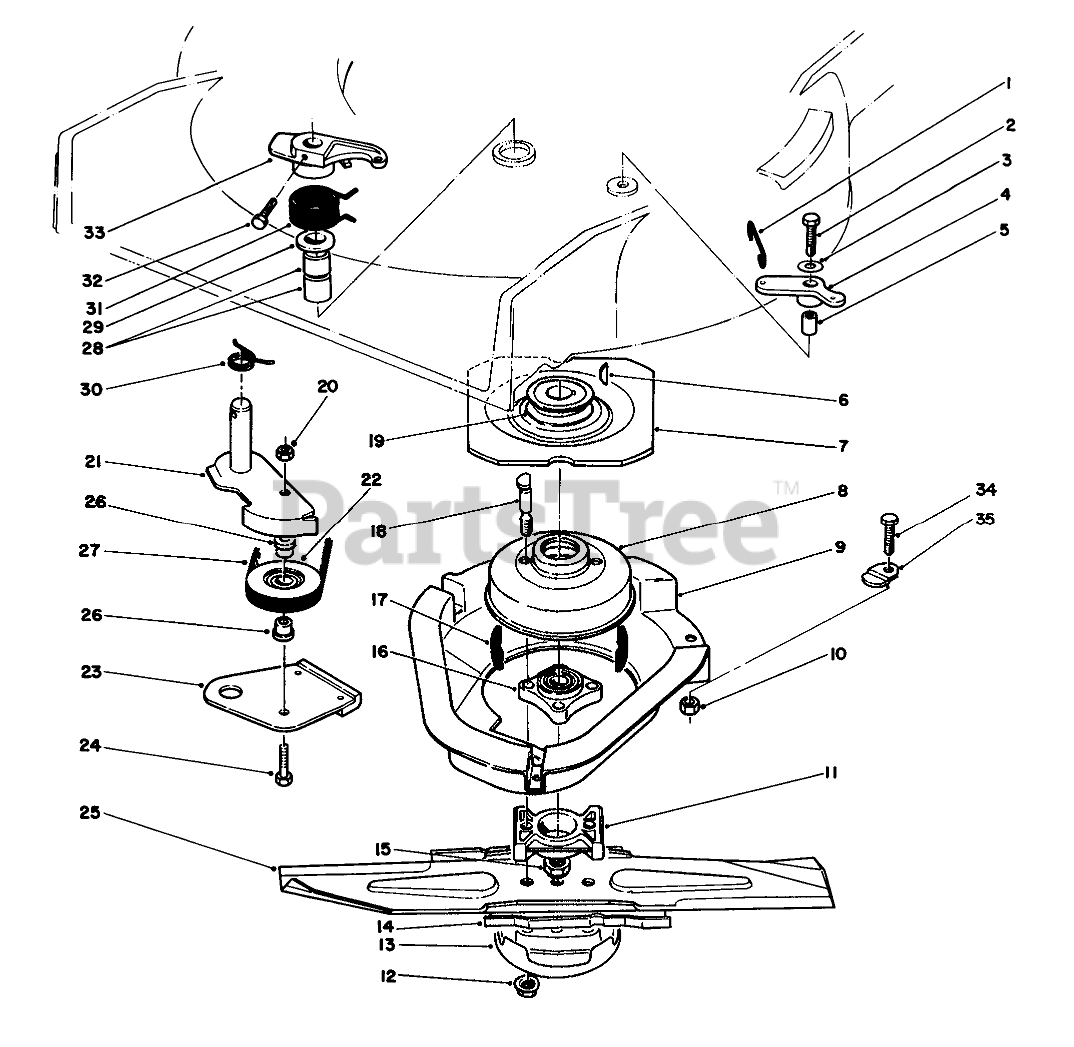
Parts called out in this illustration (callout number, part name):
1	LINK-CONTROL
2	Capscrew
3	WASHER-PLAIN
4	BELLCRANK
5	SLEEVE-BELLCRANK
6	KEY-WOODRUFF
7	Flywheel
8	Drum-Brake
9	Shield
10	NUT-LOCK, NI
11	SPACER-BLADE
12	NUT-LOCK
13	CUP-SCALP, ANTI
14	Accelerator
15	NUT-LOCK, NI
16	HUB ASM
17	DAMPENER-VIBRATION
18	BOLT-BLADE
19	PULLEY-DRIVER
20	NUT-LOCK, NI
21	ARM-IDLER
22	PULLEY-IDLER
23	BRAKE PLATE ASM
24	SCREW-HH
25	Blade
26	SPACER-PULLEY, IDLER
27	V-BELT
28	BEARING
29	WASHER
30	SPRING-TORSION
31	SPRING-TORSION
32	SCREW-HH
33	LEVER
34	SCREW-HH
35	SHIELD-RETAINER
